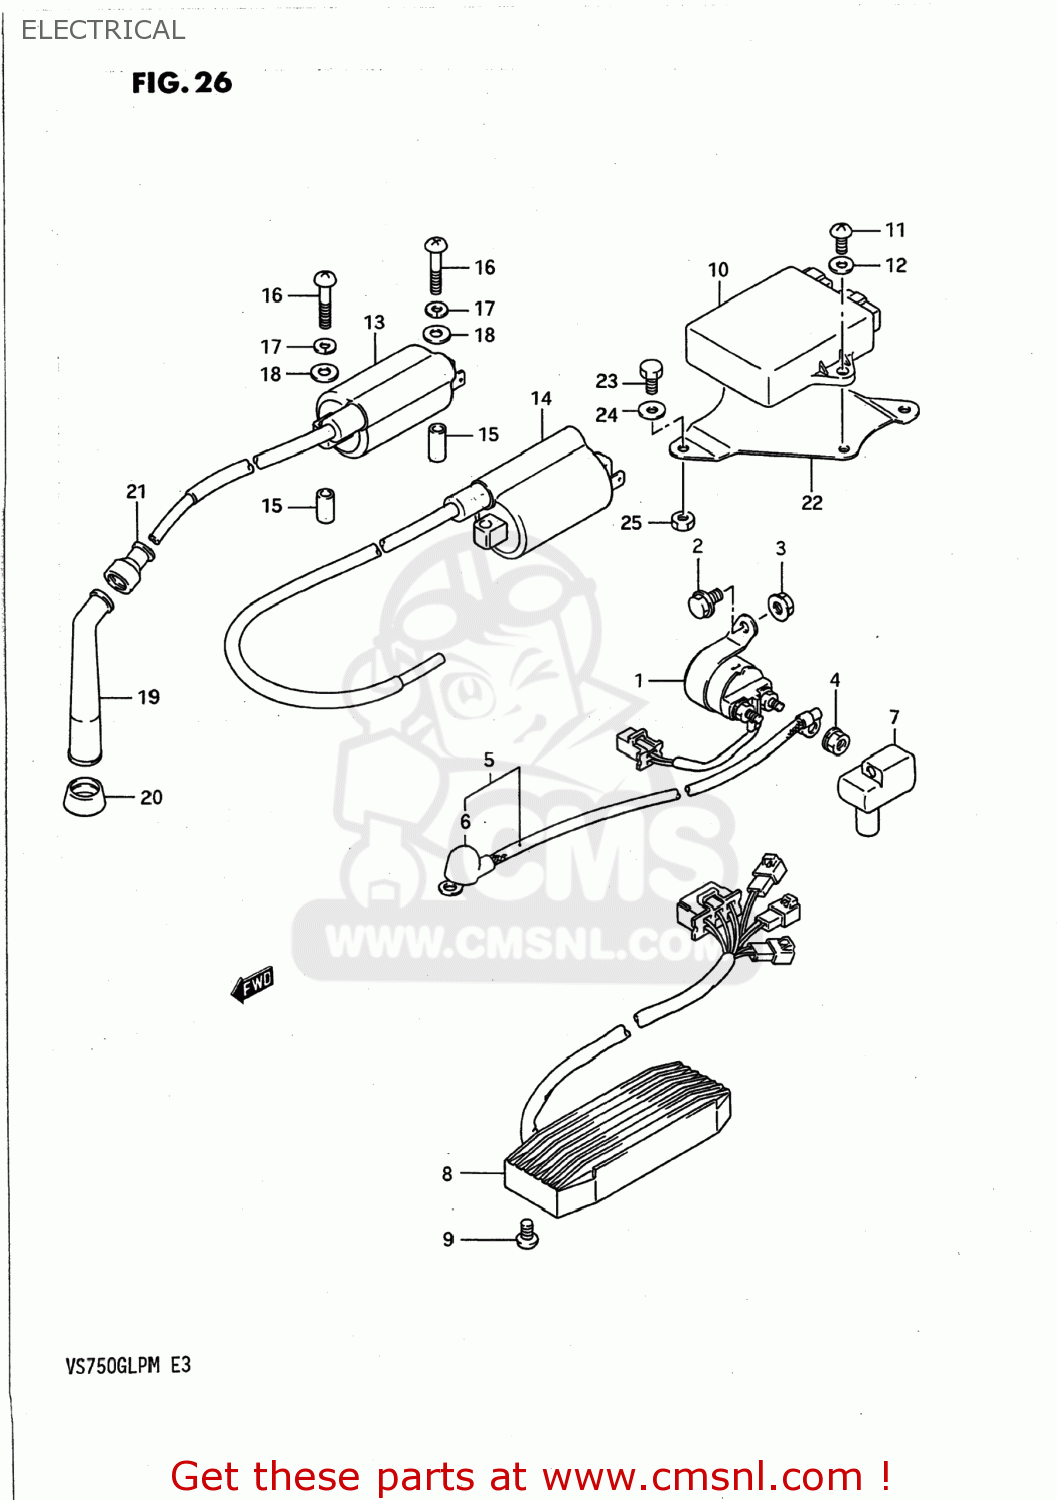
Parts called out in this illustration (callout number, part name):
1	RELAY ASSEMBLY,STARTING MOTOR
2	BOLT
3	NUT
4	NUT
5	WIRE,STARTER MOTOR LEAD
6	CAP,STARTER MOTOR TERMINAL
7	CAP,STARTER RELAY
8	RECTIFIER ASSY
9	BOLT
10	IGNITER UNIT ASSEMBLY
11	SCREW
12	WASHER, LOWER
13	COIL ASSEMBLY,IGNITION
14	COIL ASSEMBLY,IGNITION
15	SPACER(6.4X10X19)
16	SCREW (5X38)
17	LOCK WASHER
18	WASHER
19	CAP,SPARK PLUG
20	SEAL,SPARK PLUG CAP
21	SEAL,HIGH TENSION CORD
22	PLATE,IGNITOR FITING
23	BOLT
24	WASHER,LOCK
25	NUT
